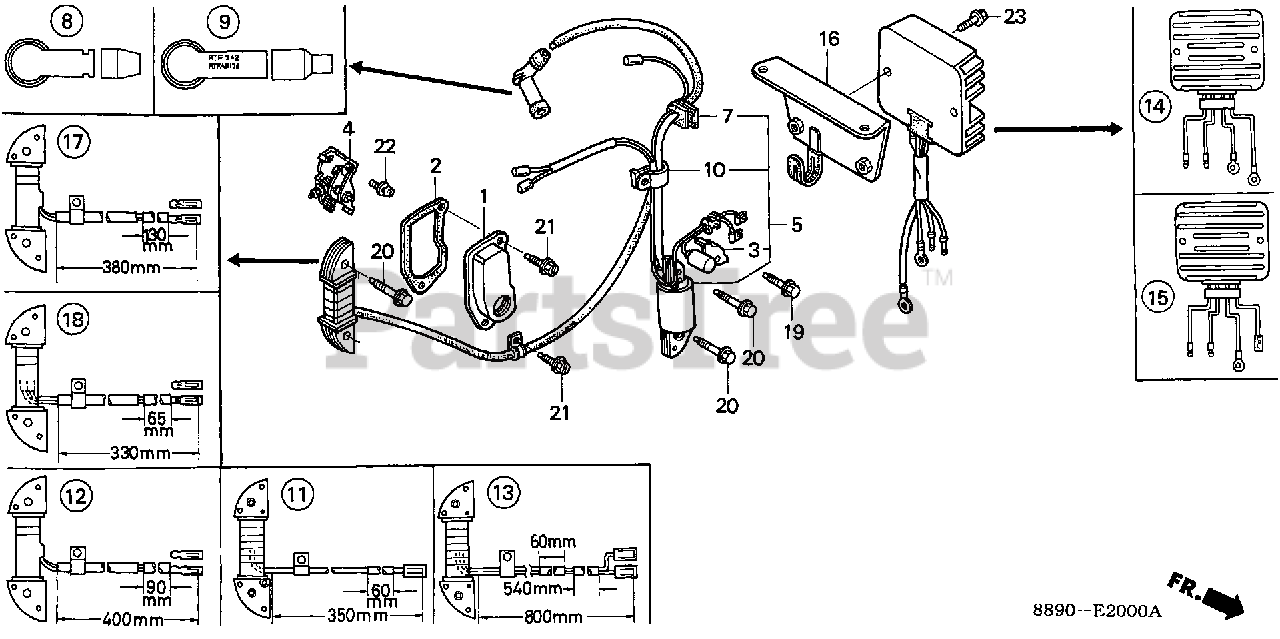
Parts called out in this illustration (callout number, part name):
1	COVER, BREAKER
2	GASKET, COVER
3	CONDENSER
4	POINTS ASSY.
5	COIL ASSY., IGNITION (LAMP)
7	GROMMET, WIRE
8	TERMINAL ASSY., IGNITION (NOT AVAILABLE)
8	TERMINAL ASSY., IGNITION
9	CAP ASSY., NOISE SUPPRESSOR
10	CLAMP, IGNITION WIRE
17	COIL ASSY., CHARGE (SILICON RECTIFIER) (NOT AVAILABLE)
19	BOLT, FLANGE (6X12) (CT200)
20	BOLT, FLANGE (6X32) (CT200)
21	BOLT, FLANGE (5X10)
22	SCREW-WASHER (5X12)
